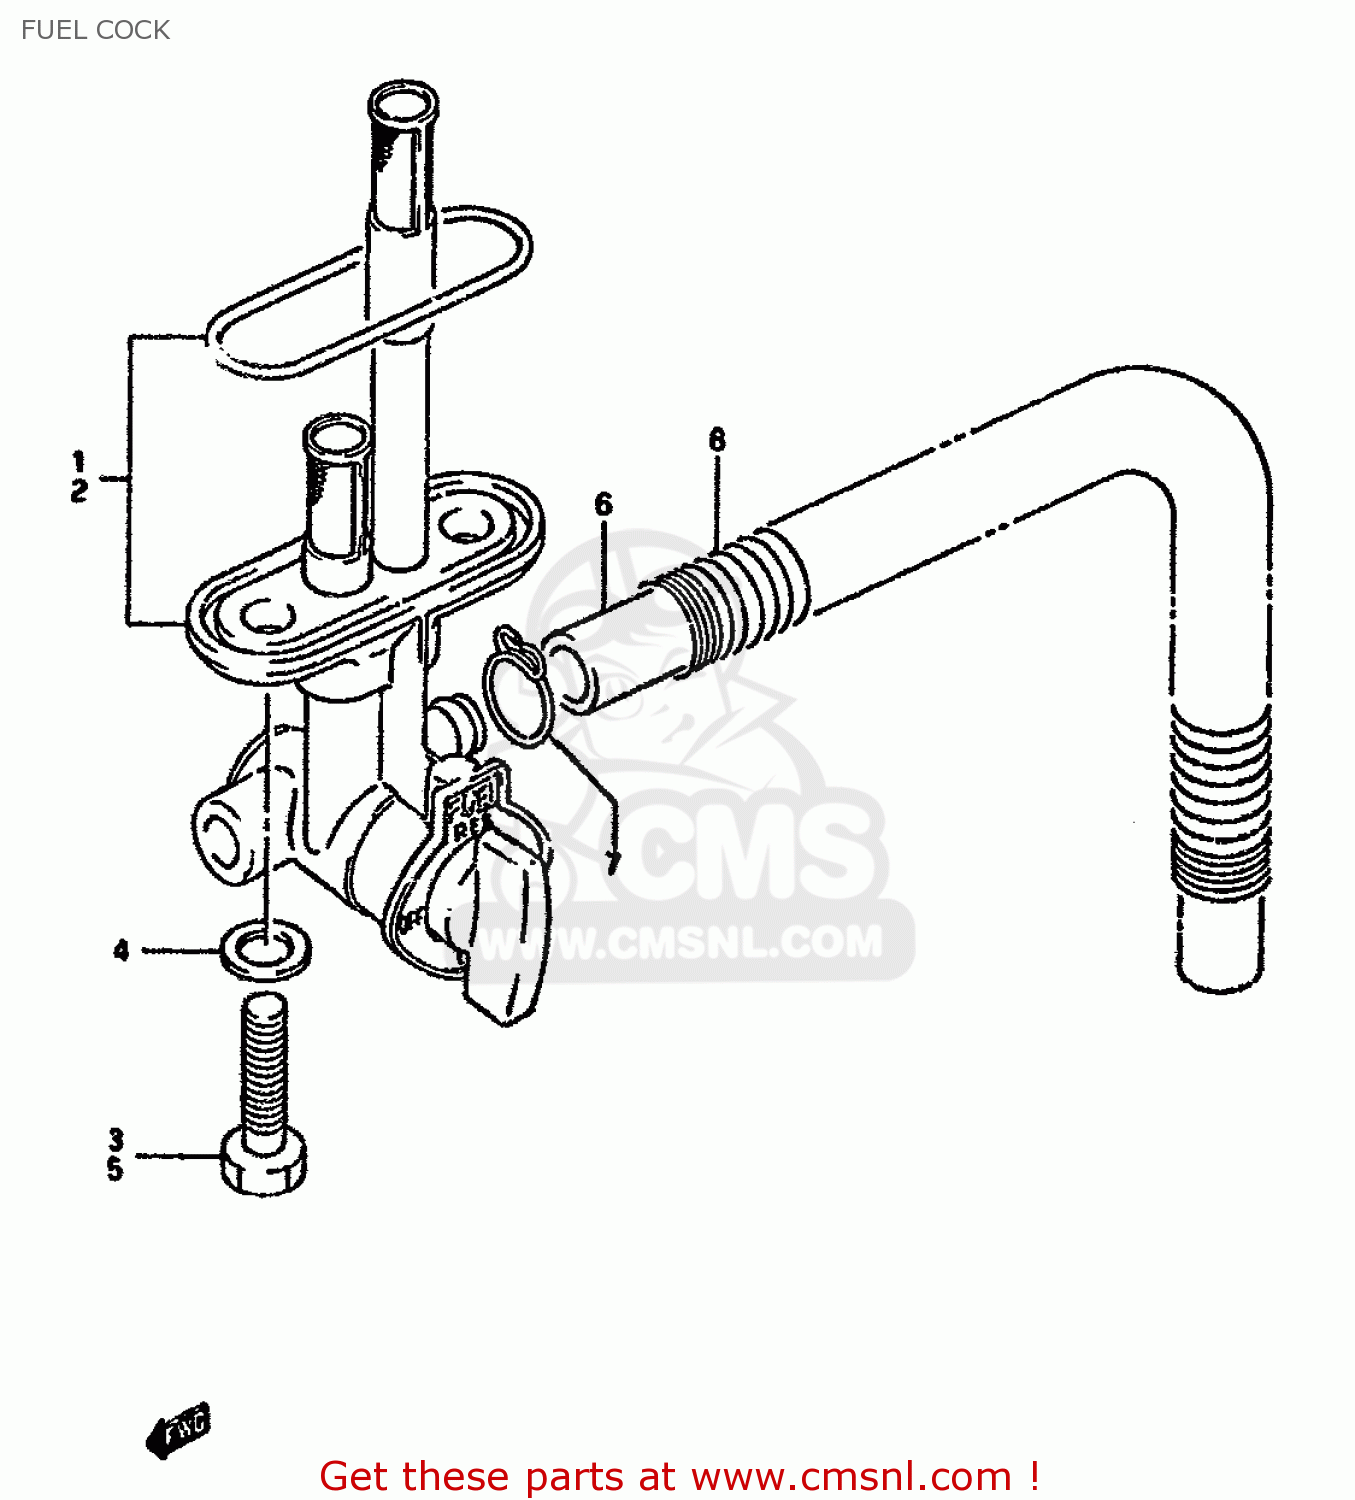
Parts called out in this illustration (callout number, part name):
1	COCK ASSY,FUEL
2	COCK ASSY,FUEL
3	BOLT(6X20)
4	GASKET(6.4X11.5X0.8) (NAS)
5	SCREW
6	HOSE
7	CLIP
8	SPRING
